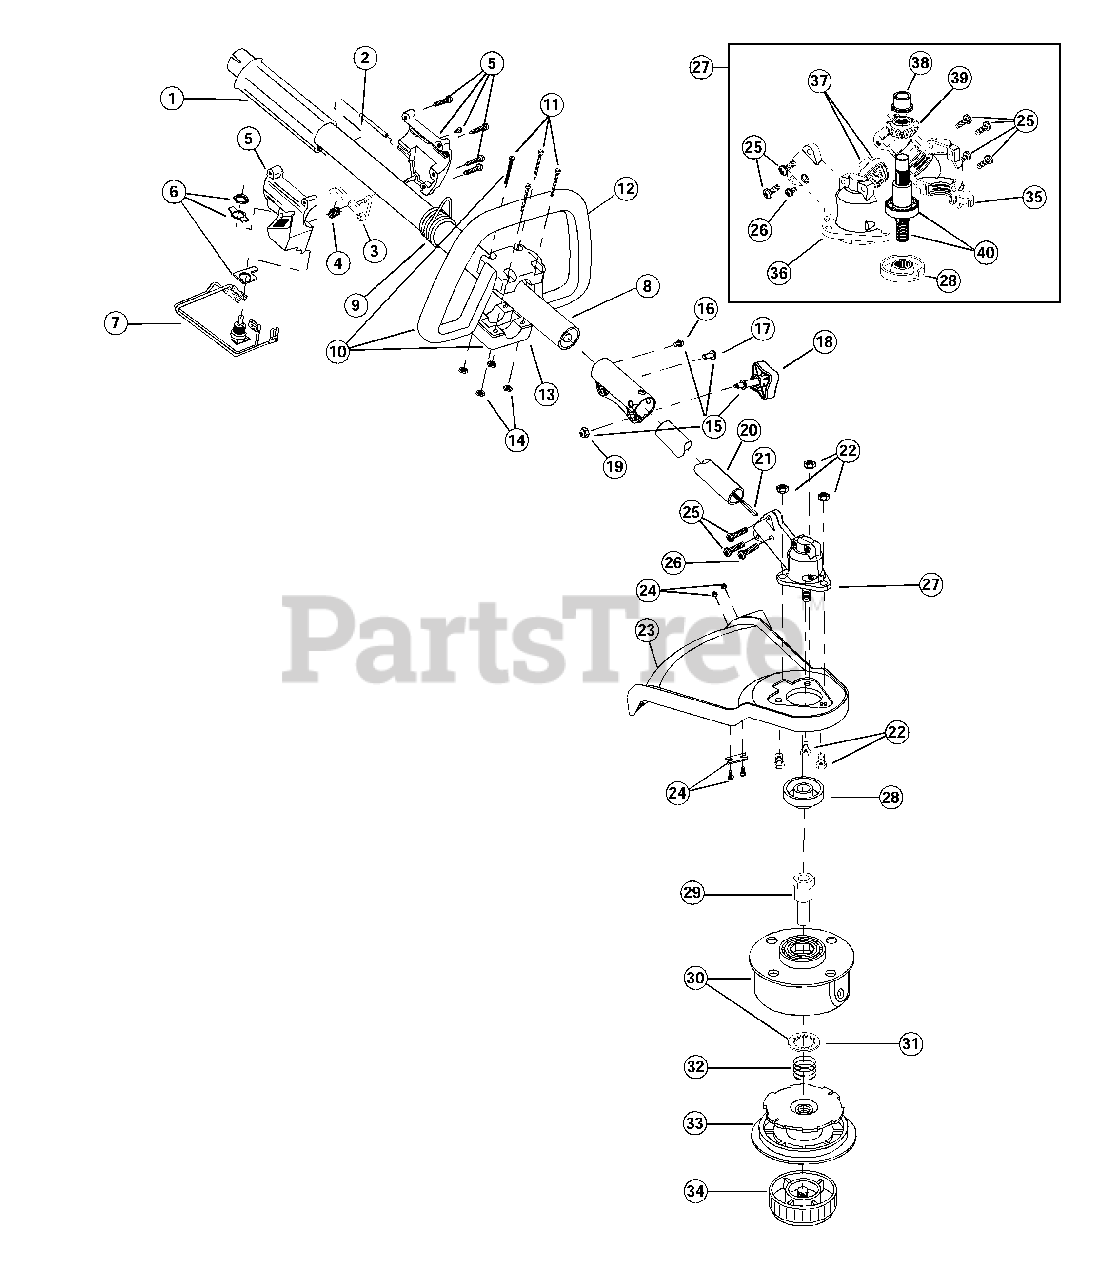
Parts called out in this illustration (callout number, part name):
2	Throttle Cable Assembly
3	Throttle Trigger
4	Throttle Trigger Spring
5	Throttle Trigger Assembly
6	Switch Assembly
7	Wire Lead Assembly
8	Upper Drive Shaft Housing Assembly
9	Shoulder Harness Clamp
10	D-Handle Assembly
12	Loop Handle
13	Bottom Clamp
15	Split Boom Coupler
18	Adjustment Knob
19	Knob Retaining Nut
20	Lower Drive Shaft Housing
21	Drive Shaft
22	Shield Mount Screw Assembly
23	Shield & Blade Assembly
24	Blade Assembly
25	Gearbox Mounting Hardware
26	Anti-Rotation Screw
27	2 piece Gearbox Assembly
28	Blade Driver
29	Spool Shaft
30	Outer Spool & Eyelet Assembly
31	Retainer
32	Spring
33	Inner Reel
34	Bump Head Knob Assembly
35	Left Housing
36	Right Housing
37	Pinion Gear Assembly
38	Output Shaft Bushing
39	Output Shaft Gear
40	Output Shaft Assembly
